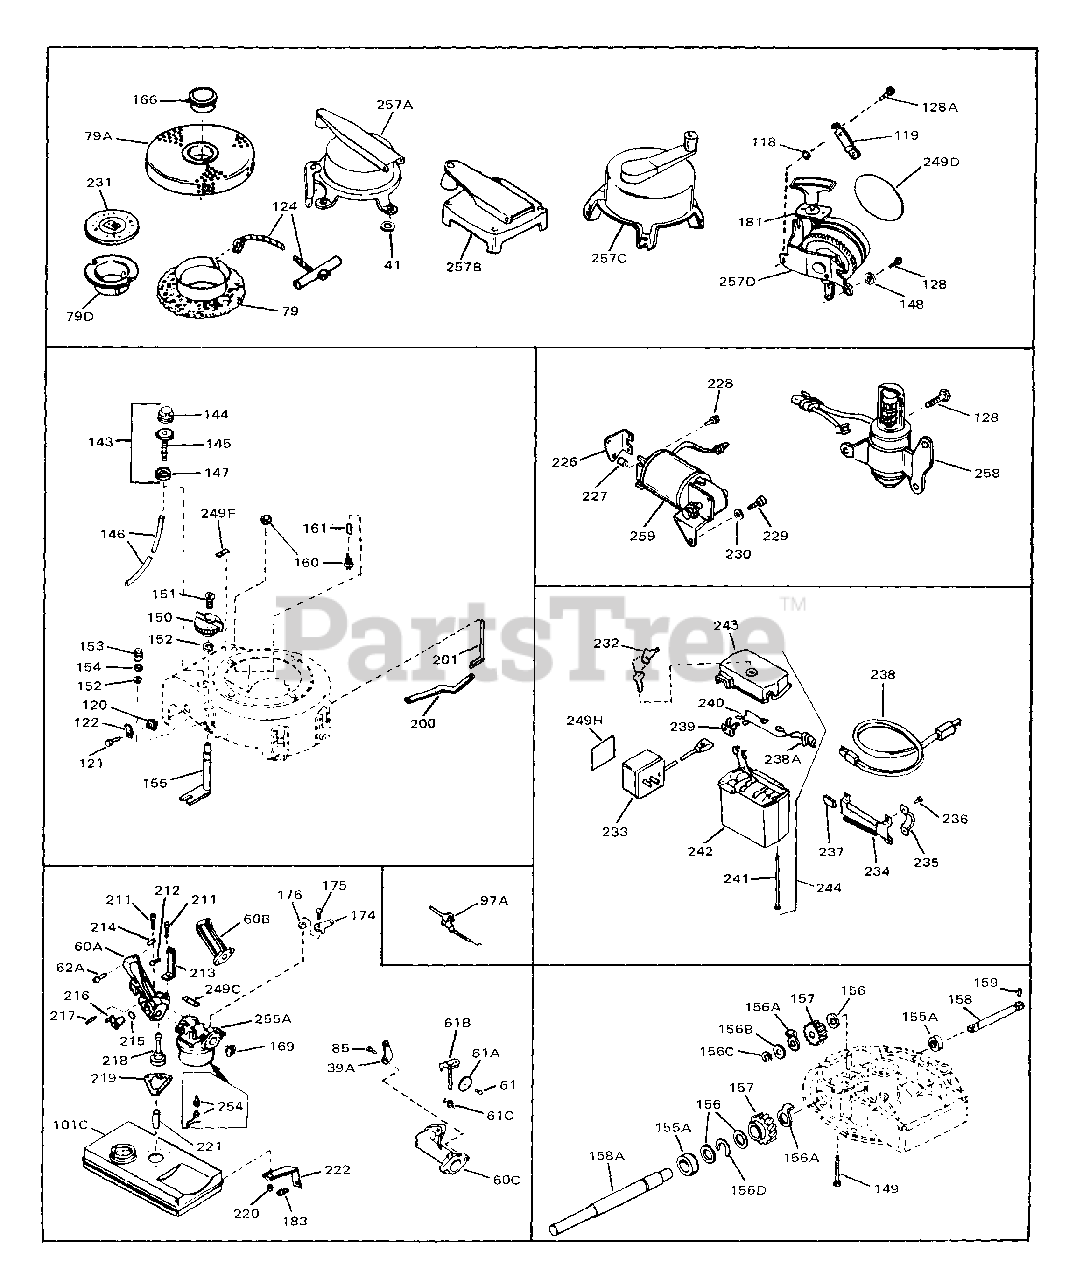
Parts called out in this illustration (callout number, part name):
39A	Lever, Speed adj.
41	Washer, Lock 1/4
41	Washer, Flat 1/2
41	Washer, Flat 1/4
79	Pulley, Rope starter
79D	Cup, Starter
85	Screw, Hex hd. cap, 1/4-28 x 7/8
85	Screw, Hex hd. cap, 1/4-28 x 1
85	Screw & Lockwasher, Hex hd. cap, 1/4- 20 x 1
124	Rope Assy., Starter
128	Screw, Hex washer hd. taptite, 1/4-20 x 1/2
148	Washer, 1/4
155A	Seal, Oil
156	Washer, Thrust
156A	Washer, Tang
156B	Washer, Flat
156C	Ring, Retaining
157	Gear, Worm
158	Shaft, P.T.O.
160	Switch, Toggle
161	Cap, Toggle switch
166	Plug, Screen
181	Rope Guide Assy.
181	Bracket Assy.
183	Screw, Slotted hex washer hd., 1/4-20 x 7/16
254	Inlet Needle, Seat & Clip Assy.
255A	Carburetor
